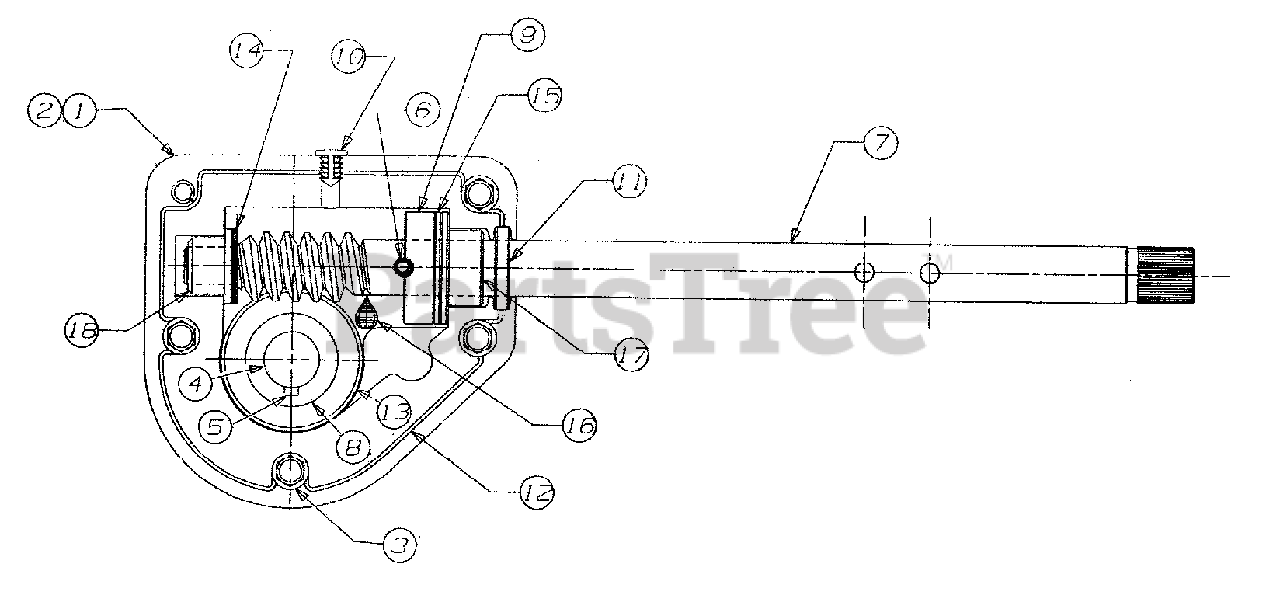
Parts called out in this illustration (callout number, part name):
1	Housing-L.H.
2	Housing-R.H.
3	Screw
4	Spiral Axle 24"
5	Key
6	Pin-Spiral
7	Shaft-Worm
8	Gear-Worm
9	Collar-Thrust
11	Seal-Oil
12	Locktite 5699
13	Washer-Flat
14	Washer-Flat
15	Washer-Flat
16	Grease
17	Bearing-Flange
18	Bearing-Flange
